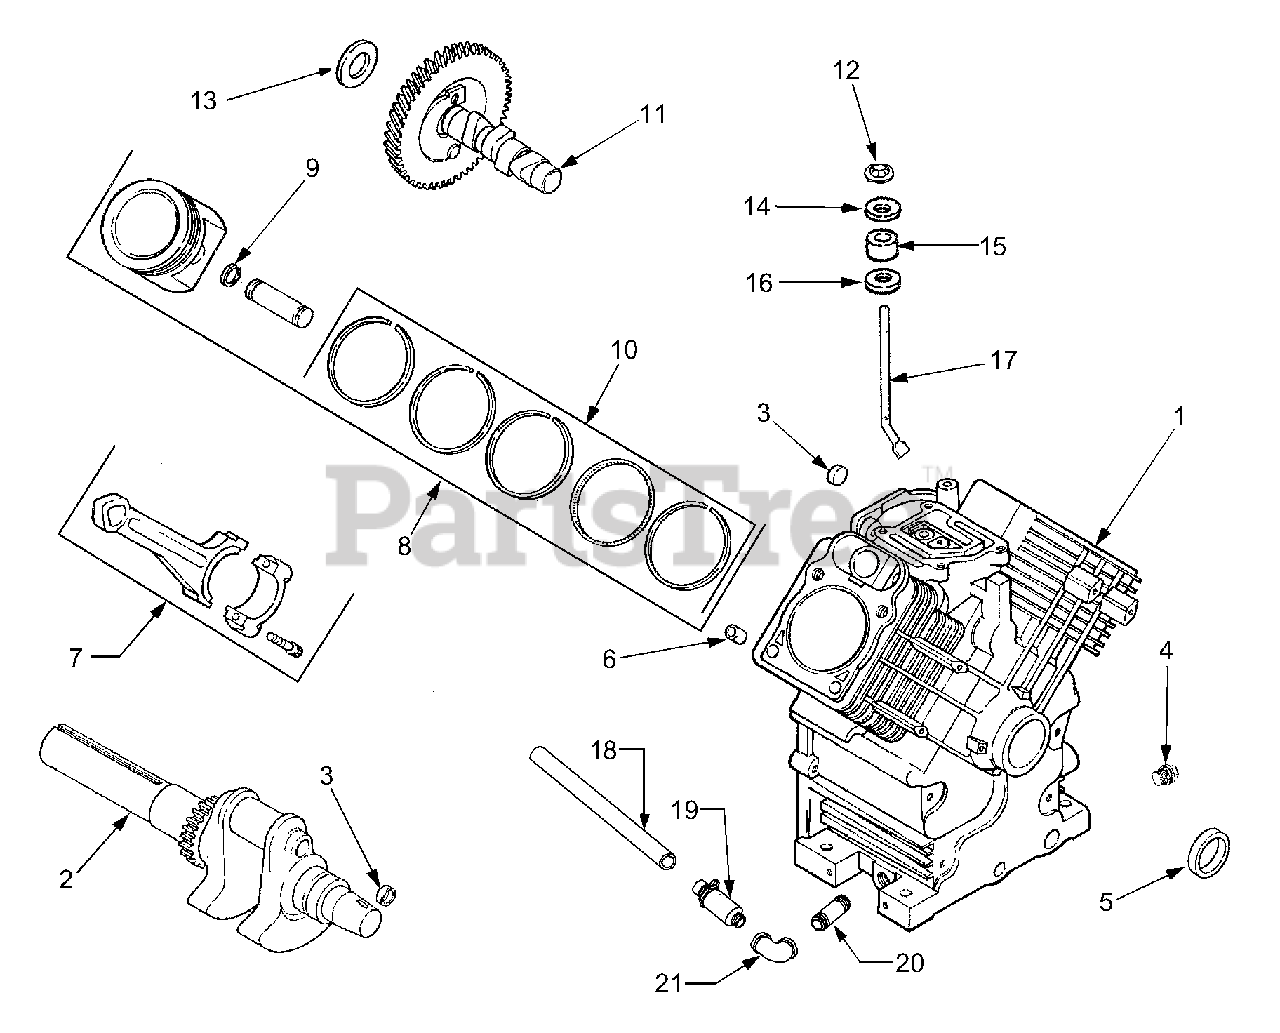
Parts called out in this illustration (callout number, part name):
1	Engine, Complete
2	Crankshaft
3	Plug, Cup
4	Plug, Hex Head, 3/8 NPTF
5	Seal, Oil
6	Pin, Dowel Locating
7	Rod, Connecting, Std
8	Piston w/Ring Set, Std
9	Retainer, Piston Pin
10	Ring Set, Std & .003
11	Camshaft
12	Ring, Retainer
13	Shim, Camshaft, .0320
14	Washer, Nylon
15	Seal, Governor Cross Shaft
16	Washer, Plain
17	Shaft, Governor Cross
18	Hose, Oil Drain
19	Drain, Oil
20	Pipe, Straight
21	Elbow, 90°.
